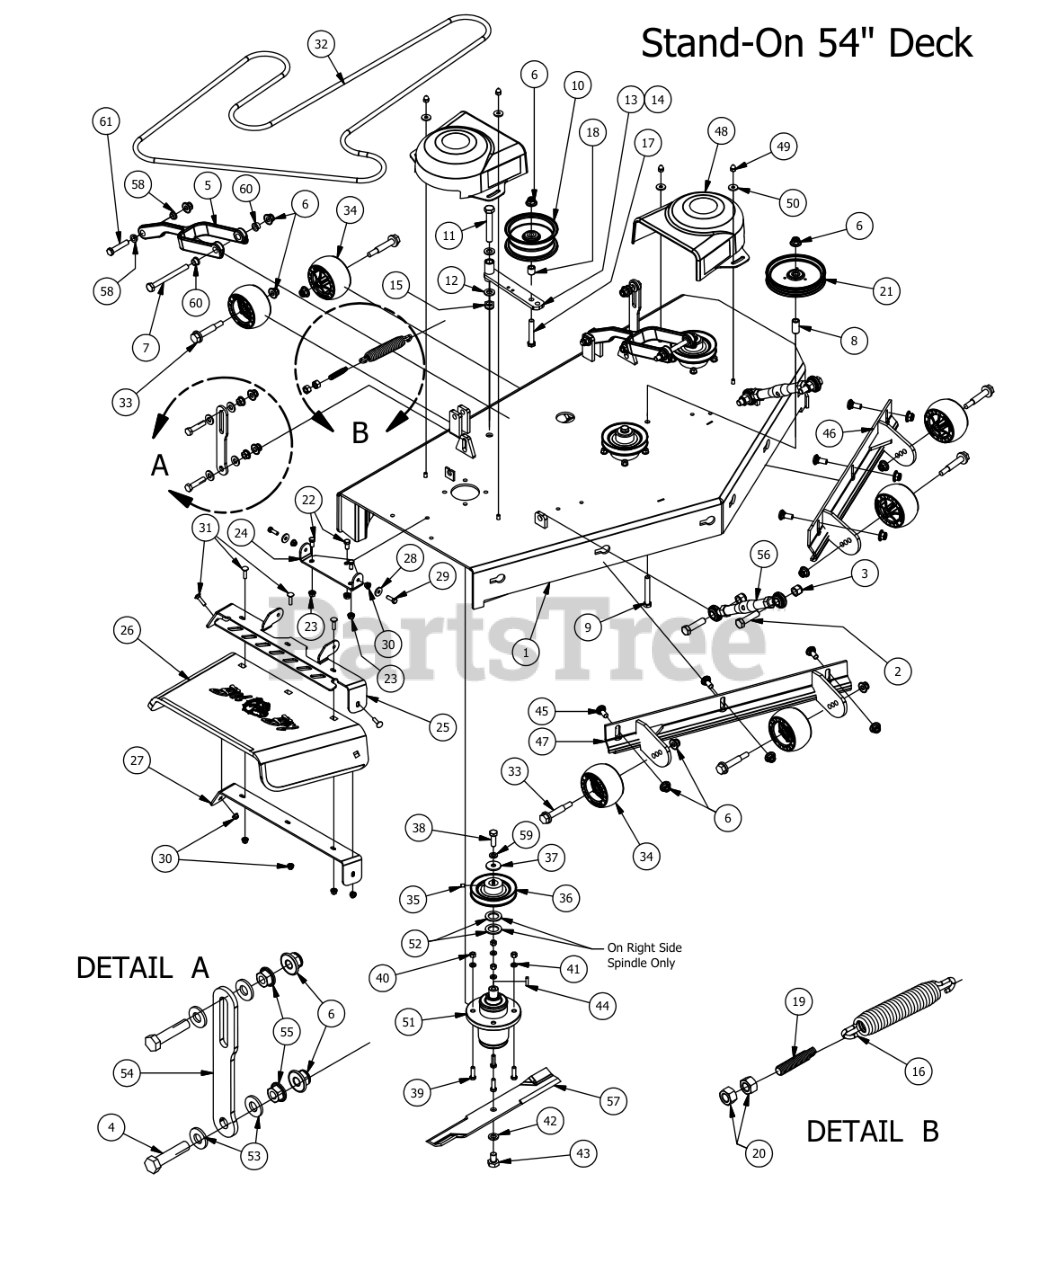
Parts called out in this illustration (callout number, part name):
1	54" 2015 Stand-On Deck (Welded Assembly)
2	5/8" x 2 1/2" Hex Bolt
3	5/8 Std NC Nylock Nut
4	1/2-13X 2-1/4 GR Hex Bolts
5	Deck Arm Assembly
6	1/2-13 Nylon Flange Nut
7	1/2" x 5 1/2" Bolt
8	.502 ID X.750 OD X 1.500 Long Spacer
9	1/2 x 3 1/2 Flange Bolt Grade 8
10	5 3/4" Deck Idler Pulley
11	5/8" x 4" Hex Bolt
12	.630 ID Plastic Washer
13	Deck Idler
14	Deck Idler Arm Assembly
15	5/8" Nylock (1/2 Jam)
16	2009 Deck/Pump Idler Spring
17	1/2-13 x GR 5 Hex Bolt Zinc
18	Spacer 3/4 OD x 1/2 ID x 3\4 Length
19	All Thread-Pump Idler Tensioner
20	1/2" Hex Nut
21	5-3/4 Idler Pulley-Don Dye
22	3/8" x 3/4" Hex Bolt
23	3/8" Flange Nut
24	Discharge Chute Hanger (deck mounted)
25	60" Discharge Chute Upper Hanger
26	Rubber Discharge Chute
27	60" Discharge Lower Bracket
28	.360 ID Plastic Washer
29	5/16" x 1" Bolt
30	5/16" Nylock Flange Nut Zinc
31	5/16" x 1 1/4" Carriage Bolt
32	42" Deck Belt - B120
33	Deck Wheel Bolt
34	Anti-Scalp Rollers
35	5/16 Set Screw
36	5" Spindle Deck Pulley
37	1/2 Belleville Washer
38	1/2"-20 x 1 1/2 - Grade 5 Fine Thread Bolt
39	3/8" x 1 1/4" Hex Bolt
40	3/8-16 Hex Nuts Zinc
41	3/8" Lock Washer
42	5/8" Lock Washer
43	5/8" x 1 1/2" Grade 8 Hex Bolt (Fine)
44	1/4" x 1" Key
45	1/2" x 1 1/4 Carriage Bolt
46	54 Deck Adustable Front (Left)
47	54 Deck Adustable Front (Right)
48	Pulley Cover
49	Acorn nut-pulley Cover
50	.360 ID Plastic Washer-Black
51	OUTLAW SPINDLE ASSEMBLY
52	1 1/8" Flat Spacer
53	.505 Nylon Spacer
54	Longer deck hanger
55	1/2" Flange Nut
56	Turnbuckle
57	54" Deck Fusion Blade For Outlaw
58	Flange Bushing For Lower Deck Arm
59	1/2" Lock Washer
60	Flange Bushing For Upper Deck Arm
61	1/2" x 3" Hex Bolt
